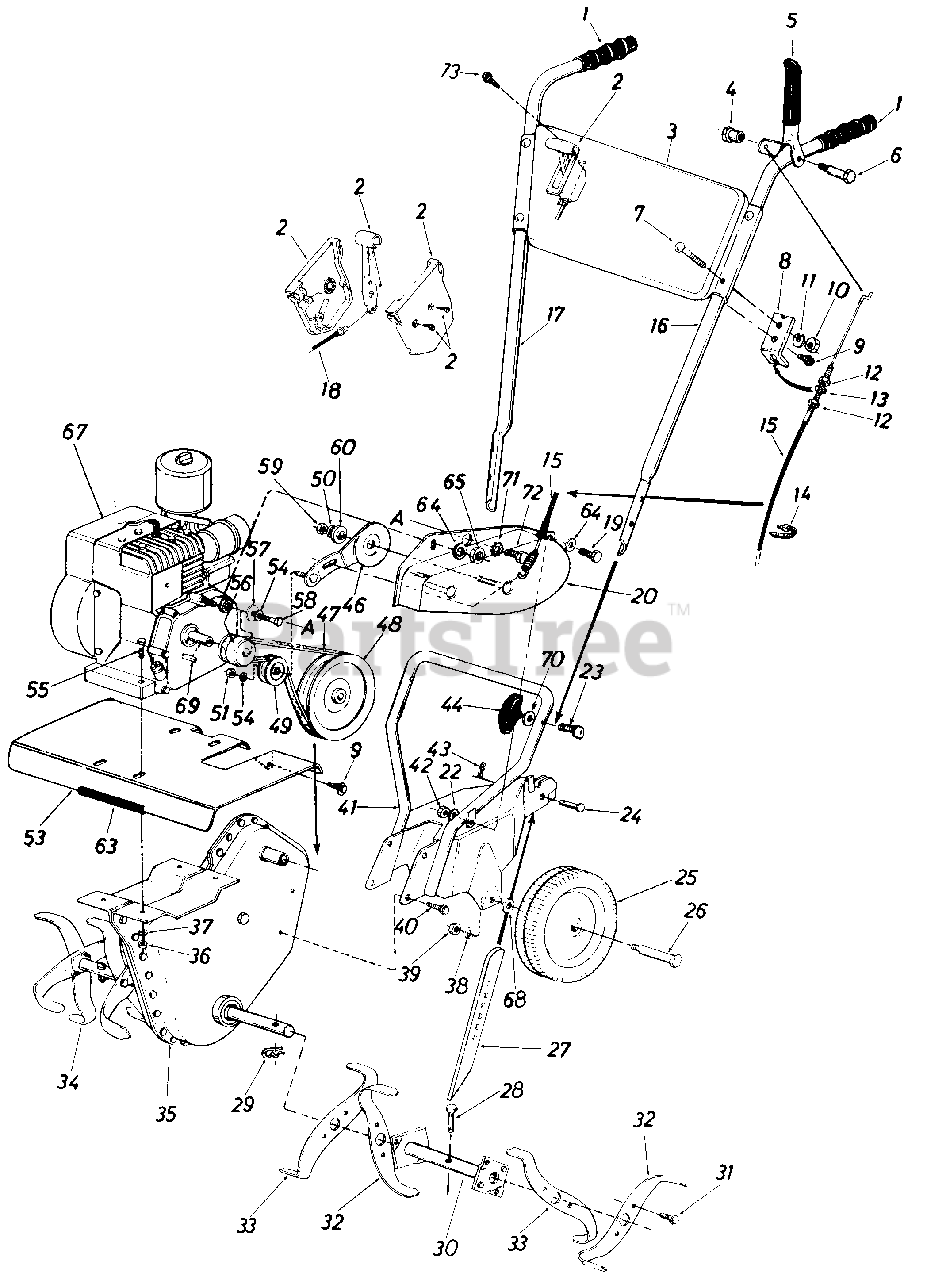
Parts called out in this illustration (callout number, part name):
2	Throttle Control Box Ass'y.
3	Handle Panel
4	Shoulder Nut
5	Clutch Grip Ass'y.
6	Shoulder Bolt 3/8 x 1.160" Lg.
7	Carriage Bolt 5/16-18 x 1.5" Lg.*
8	Cable Support Bracket
9	Hex Wash. Hd. Self-Tap Scr. 1/4-20 x 50" Lg.
10	Hex Nut 5/16-18 Thd.*
11	L-Wash. 5/16" I.D.
12	Hex Jam Nut 5/16-24 Thd.
13	L-Wash. 5/16" I.D.*
14	Cable Tie
15	Clutch Control Cable
19	Hex Bolt 1/4-20 x .75" Lg.
20	Belt Cover Ass'y.
22	L-Wash. 1/4" I.D.
23	Curved Hd. Bolt 5/16-18 x 1.75" Lg.
24	Clevis Pin
25	Wheel Ass'y. Comp. 7.0" x 1.5
26	Shoulder Bolt
29	Hairpin Cotter
36	Hex Nut 5/16-18 Thd.
37	L-Wash. 5/16" I.D.
38	L-Wash. 3/8" I.D.
39	Hex Cent. L-Nut 3/8-16 Thd.
40	Hex Wash. Hd. Self-Tap Scr. 5/16-18 x .50" Lg.
43	Internal Cotter Pin
44	Hand Knob
46	Idler Arm Ass'y.
47	Belt 3/8" x 29" Lg.
48	Chain Case Pulley 5-1/2 x 1/2"
49	Fl-Idler 2"
50	L-Wash. 5/16" I.D.
51	Hex Nut 3/8-24 Thd.
55	Hex Bolt 5/16-18 x 1.50" Lg.
56	Engine Pulley 3/8 V x .75 I.D. x 2" O.D.
57	Fl-Wash. .385" I.D. x 1.00" O.D.
58	Hex Bolt 3/8-24 x 1.00" Lg.
59	Hex Nut 5/16-18 Thd.
60	Shld. Spacer .50" Dia. x .133
63	Trim Strip-4"
64	Fl-Wash. .281" I.D. x .500" O.D.
65	Hex Cent. L-Nut 1/4-20 Thd.
67	Engine
68	Bell-Wash.
69	Square Key 3/16 x 3/4" Lg.
70	Bell-Wash.
71	Ext. L-Wash. 1/2" I.D.
72	Hex Bolt 1/2-20 x .75" Lg.
73	Self-Tap Screw #10 x .5" Lg.
